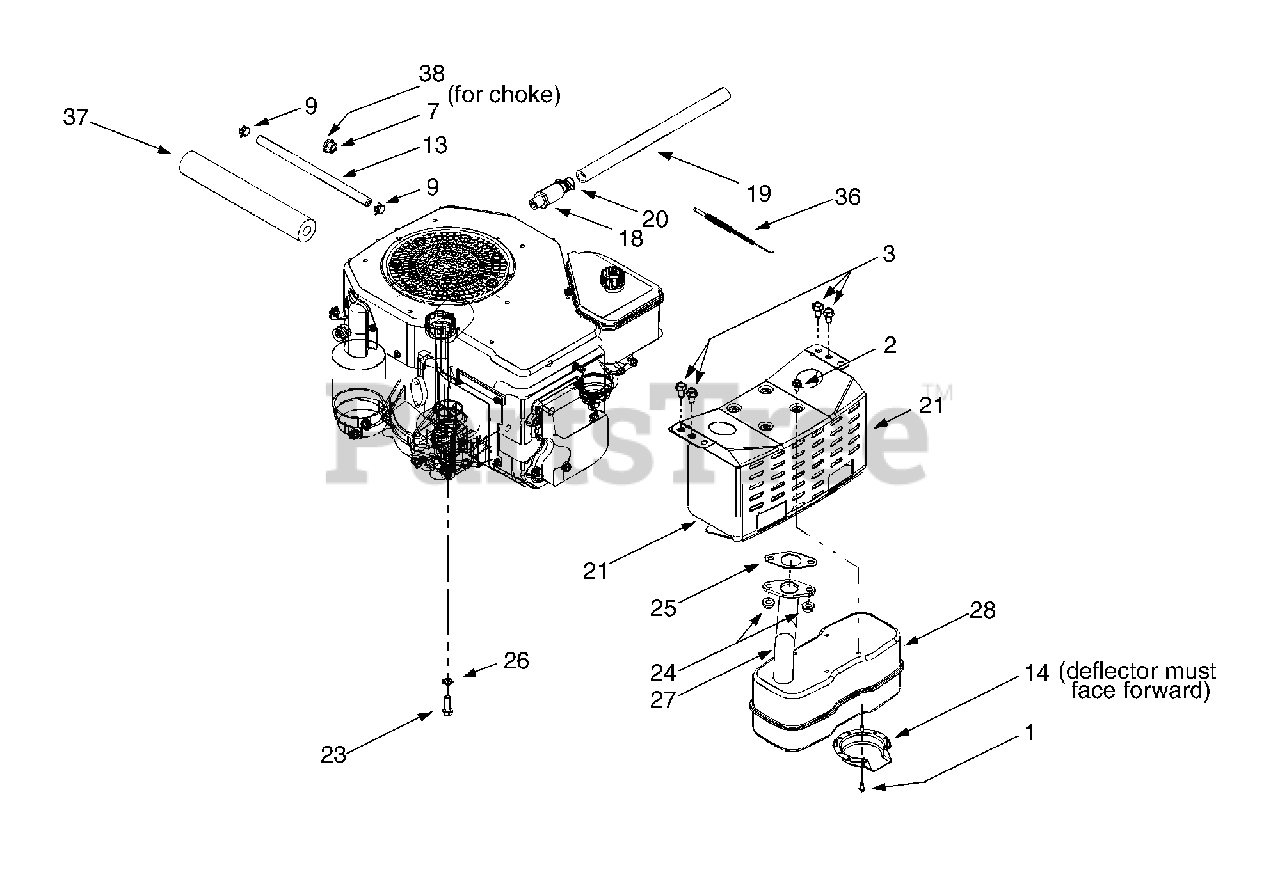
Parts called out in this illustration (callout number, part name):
1	Self-tapping Screw, #8-32 x .375
2	Self-tapping Screw, 1/4-20 x .5
3	Self-tapping Screw, 5/16-18 x .625
7	Hex Nut, 3/8-16
9	Hose Clamp
13	Fuel Line Hose
14	Muffler Deflector
18	Oil Drain Valve
19	Oil Drain Hose
20	Oil Drain Cap
23	Hex Cap Screw, M8-1.25 x 25
24	Flange Nut, M8-1.25
25	Exhaust Gasket
26	External Lock Washer, 5/16
27	Exhaust Pipe
28	Muffler, Single Inlet
36	Throttle Cable
37	Foam
38	Flat Washer, .406 x .875 x .059
